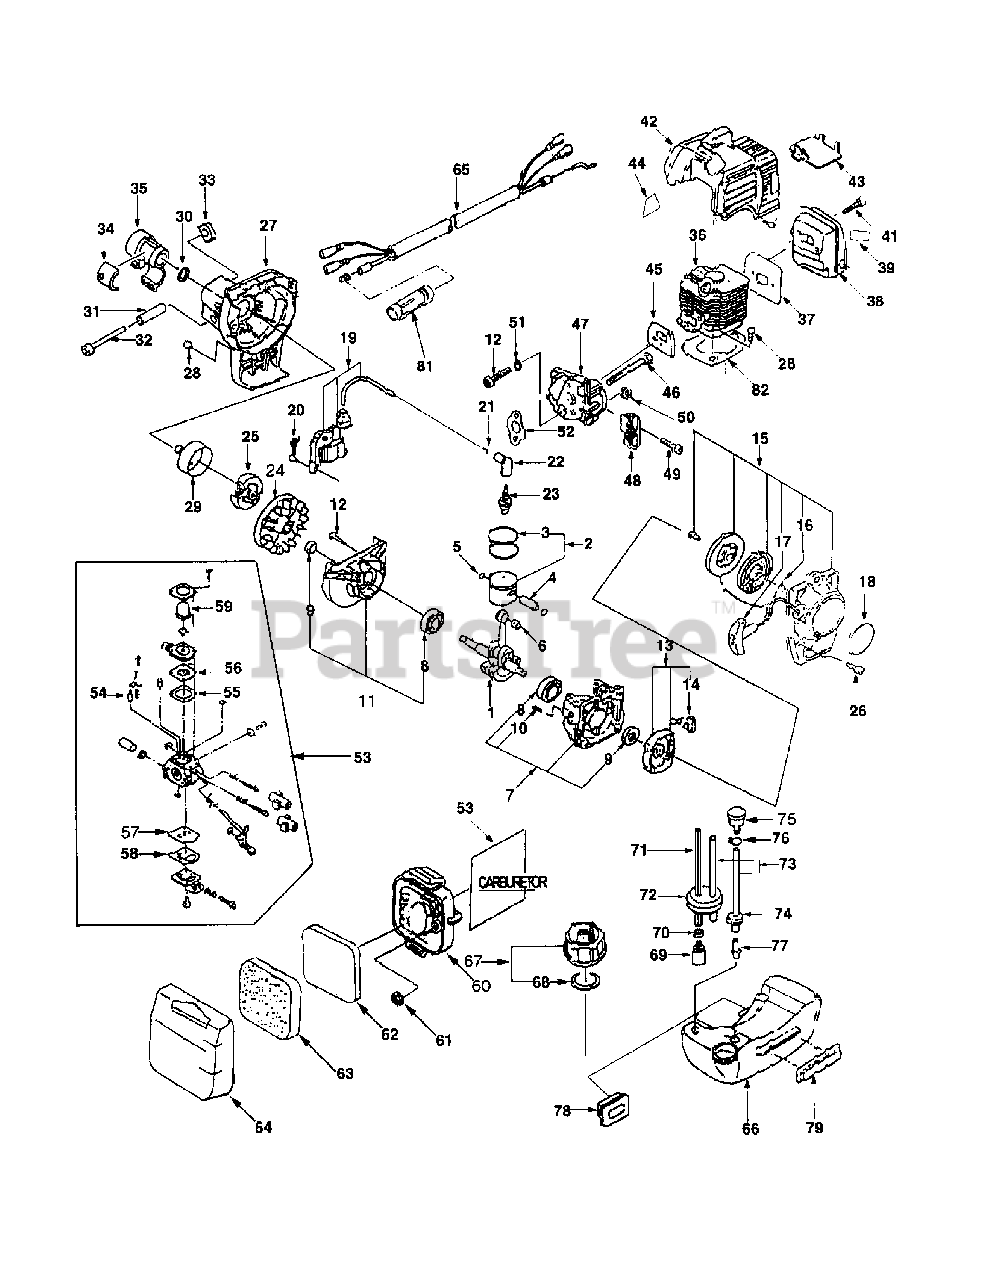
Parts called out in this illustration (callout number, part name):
1	Crankshaft
2	Piston Ass'y
3	Ring, Piston
4	Pin, Piston
5	Clip, Piston Pin
6	Needle Bearing
7	Crankcase Ass'y
8	Ball Bearing; 6201
9	Oil Seal
10	Dowel Pin
11	Crankcase Ass'y
12	Bolt; M5 X 25
13	Pulley Ass'y, Starter
15	Recoil Ass'y
16	Rope, Starter
17	Knob, Starter
18	Name Plate
19	Coil Ass'y, Ignition
20	Bolt; M4 X 20
22	Cap, Plug
23	Spark, Plug
24	Flywheel, Magneto
25	Clutch Ass'y
26	Bolt; M5 X 20
27	Housing, Blower
28	Bolt; M5 X 16
29	Drum, Clutch
30	Snap Ring; S-12
32	Bolt; M5 X 30
36	Cylinder
37	Gasket, Muffler
39	Arrester
41	Bolt; M5 X 48
42	Cowling, Cylinder
43	Baffle Plate
44	Trade Mark
45	Gasket, Insulator
46	Bolt; M5 X 56
47	Insulator
48	Adjuster
49	Bolt; M5 X 12
51	Washer
52	Gasket, Carburetor
53	Carburetor Ass'y
54	Valve, Float
56	Diaphragm, Metering
57	Diaphragm, Pump
60	Case, Air Silencer
62	Element(B), Filter Air
63	Element(A), Filter Air
64	Case, Cap
65	Wire Compl, Throttle
66	Tank, Fuel
67	Cap Ass'y, Fuel Tank
69	Filter, Fuel
71	Hose
73	Hose
75	Valve Assy, Reversing
77	Connector
79	Rubber
80	Gasket Kit
81	Holder, Wire
84	Spring, Spiral
86	Spring, Return
